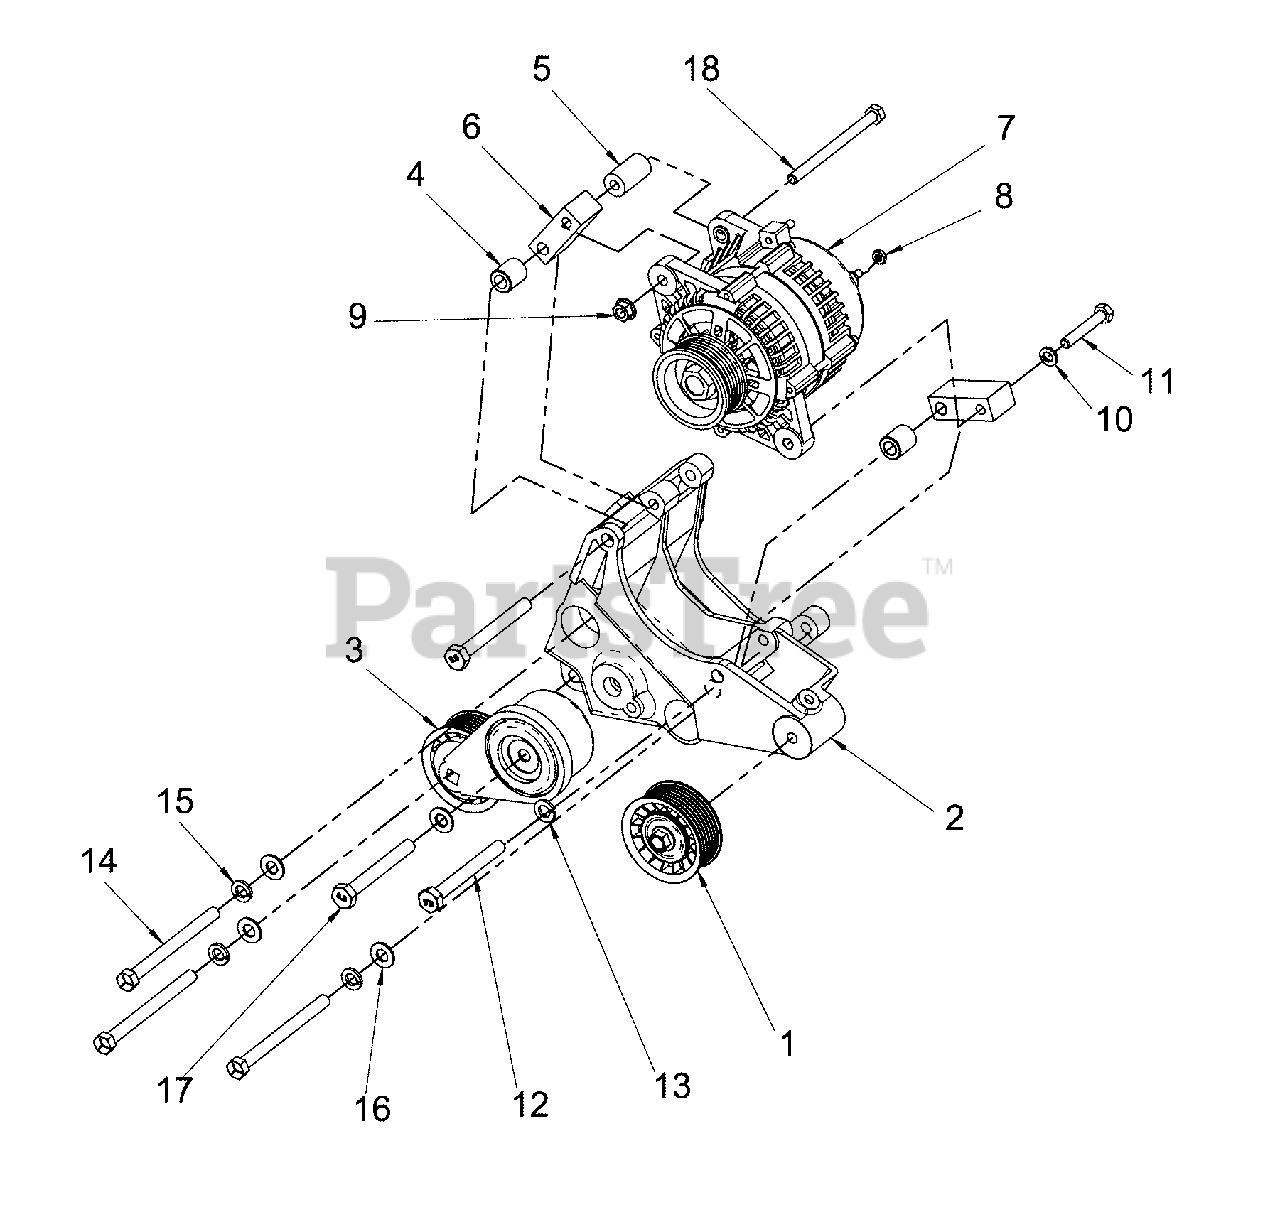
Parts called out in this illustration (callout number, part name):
2	* BRACKET
3	TENSIONER PULLEY
4	* SPACER
5	* SPACER
6	* BLOCK MOUNT
8	* NUT
9	* NUT
10	* WASHER
11	* BOLT
12	* BOLT
13	* WASHER
14	* BOLT
15	* WASHER
16	* WASHER
17	* BOLT
18	* BOLT
